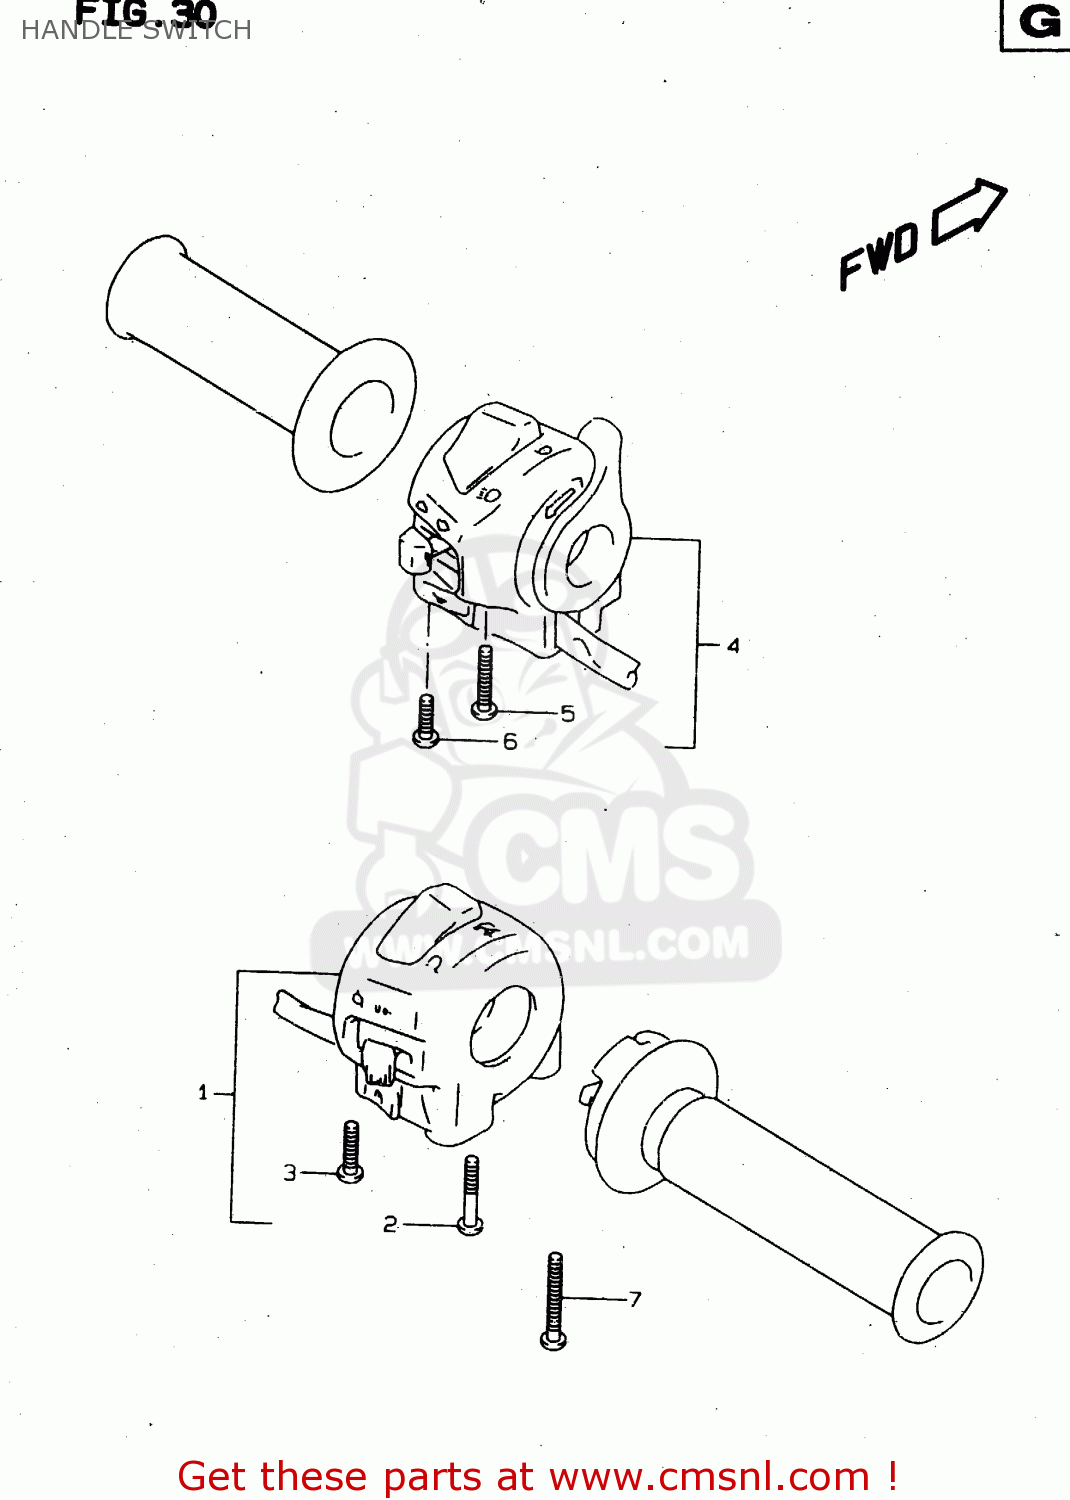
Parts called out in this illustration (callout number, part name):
1	SWITCH,HANDLE,
2	SCREW
3	SCREW
4	SWITCH ASSY,HANDLE,L
5	SCREW
6	SCREW, 5X45
7	SCREW
